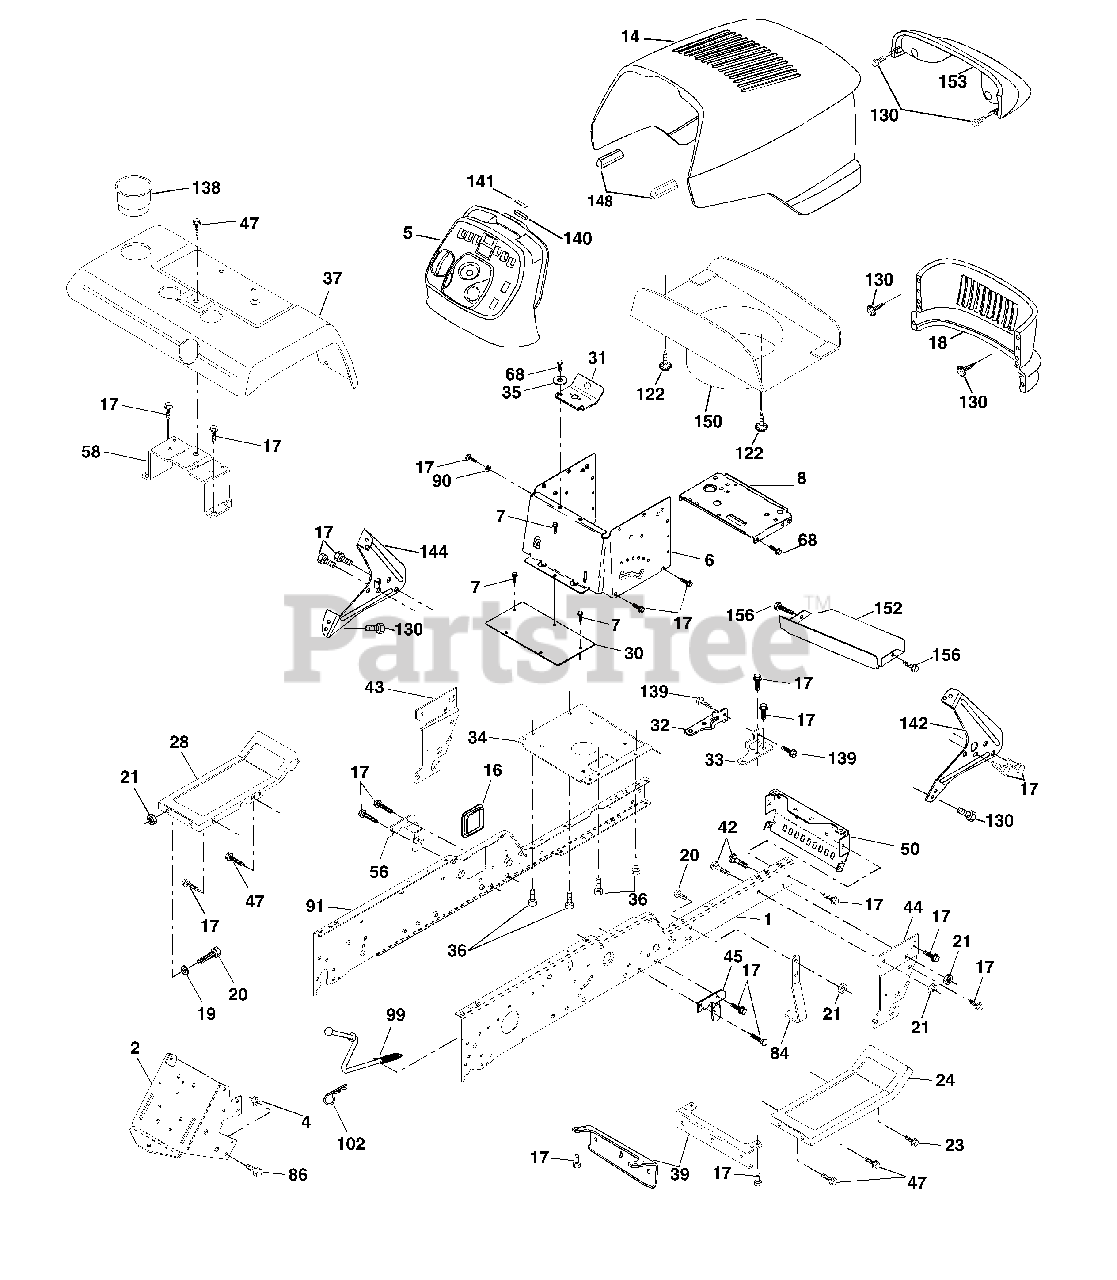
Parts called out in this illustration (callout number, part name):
1	Rail, Frame RH
2	Drawbar,Gt
4	Nut, Crownlock 7/16-14Unc
5	Dash
6	Dash Asm., Lower
7	Screw, Thd Cut 1/4-20 x 1/2
8	Support, Battery
14	Hood Asm., Pnt
16	Cover, Access
17	Screw, 3/8-16 x 3/4
18	Grille
19	Washer 13/32 x 13/16 x 12 Ga.
20	Bolt, Fin Hex 3/8-16 x 1
21	Nut, Crownlock 3/8-16 Unc
23	Screw 3/8-16 x 1
24	Footrest, RH
28	Footrest, LH
30	Saddle, Hydro 1995
31	Bracket, Supt 1-pc VGT Steering
32	Bracket, Pivot Chassis LH
33	Bracket, Pivot Chassis RH
34	Plate Asm. Engine Chassis
35	Washer 11/32 x 11/16 x 16 Ga.
36	Screw 5/16-18 x 3/4
39	Bracket, Axle Front
42	Bolt, Carriage 3/8-16 x 1
43	Bracket, Spnsn Front Lh
44	Bracket, Spnsn Front Rh
45	Bracket Asm., Susp Chassis Rh
47	Screw Thdrol 3/8-16 x 1/2 TYT
50	Bracket, Chassis Front
56	Bracket Asm., Susp Chassis Lh
58	Bracket Asm., Fender
68	Screw, Thd 5/16-18 x 1/2
84	Stop, Over Center Mower
86	Bolt, Fin Hex 7/16-14 Unc x 1
90	Washer, Lock External Tooth 3/8
91	Rail, Frame Lh
99	Rod By Pass
100	Cap Parking Brake Rod
102	Retainer,Spring
122	Screw Hex Wshd 8-18 x 7/8
130	Screw HWHD Hi-Lo #13-16 x 3/4
138	Cupholder YTGT
139	Bolt Shoulder 5/16-18 TT
140	Magnet YTGT
141	Stricker Plate YTGT
142	Bracket Dash RH
143	Skirt Grill RH
144	Bracket Dash LH
146	Skirt Grill LH
148	Extrusion Bumper
150	Duct Heat Hood
152	Shield Browning
153	Lens, Asm Headlight bar
156	Screw 5/16-18 x 3/4
